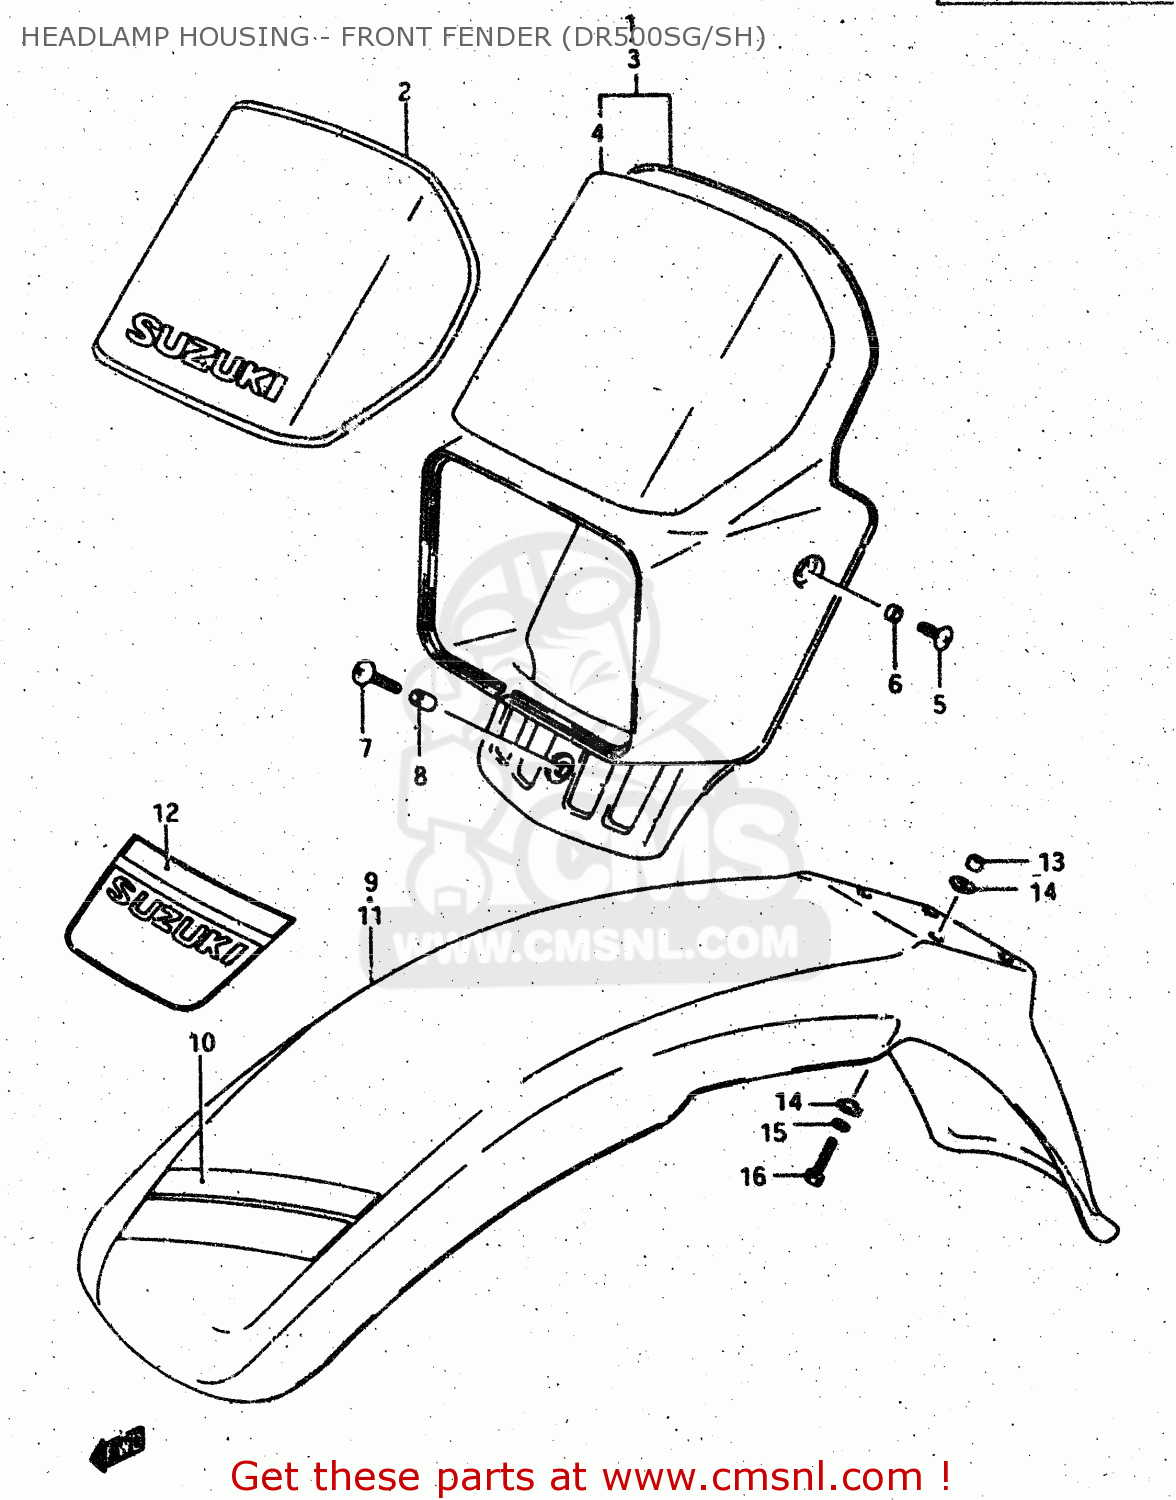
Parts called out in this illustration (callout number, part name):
1	COVER,HEADLAMP
2	TAPE SET
3	COVER,HEADLAMP
4	TAPE SET
5	SCREW 6X12
6	SPACER (6.1X8X3.5)
7	SCREW, CENTER
8	SPACER (6.1X8X12)
9	FENDER, FRONT (RED)
10	TAPE SET
11	FENDER, FRONT (BLUE)
12	TAPE SET
13	SPACER(6.1X9X7.5)
14	WASHER
15	WASHER,LOCK
16	BOLT
